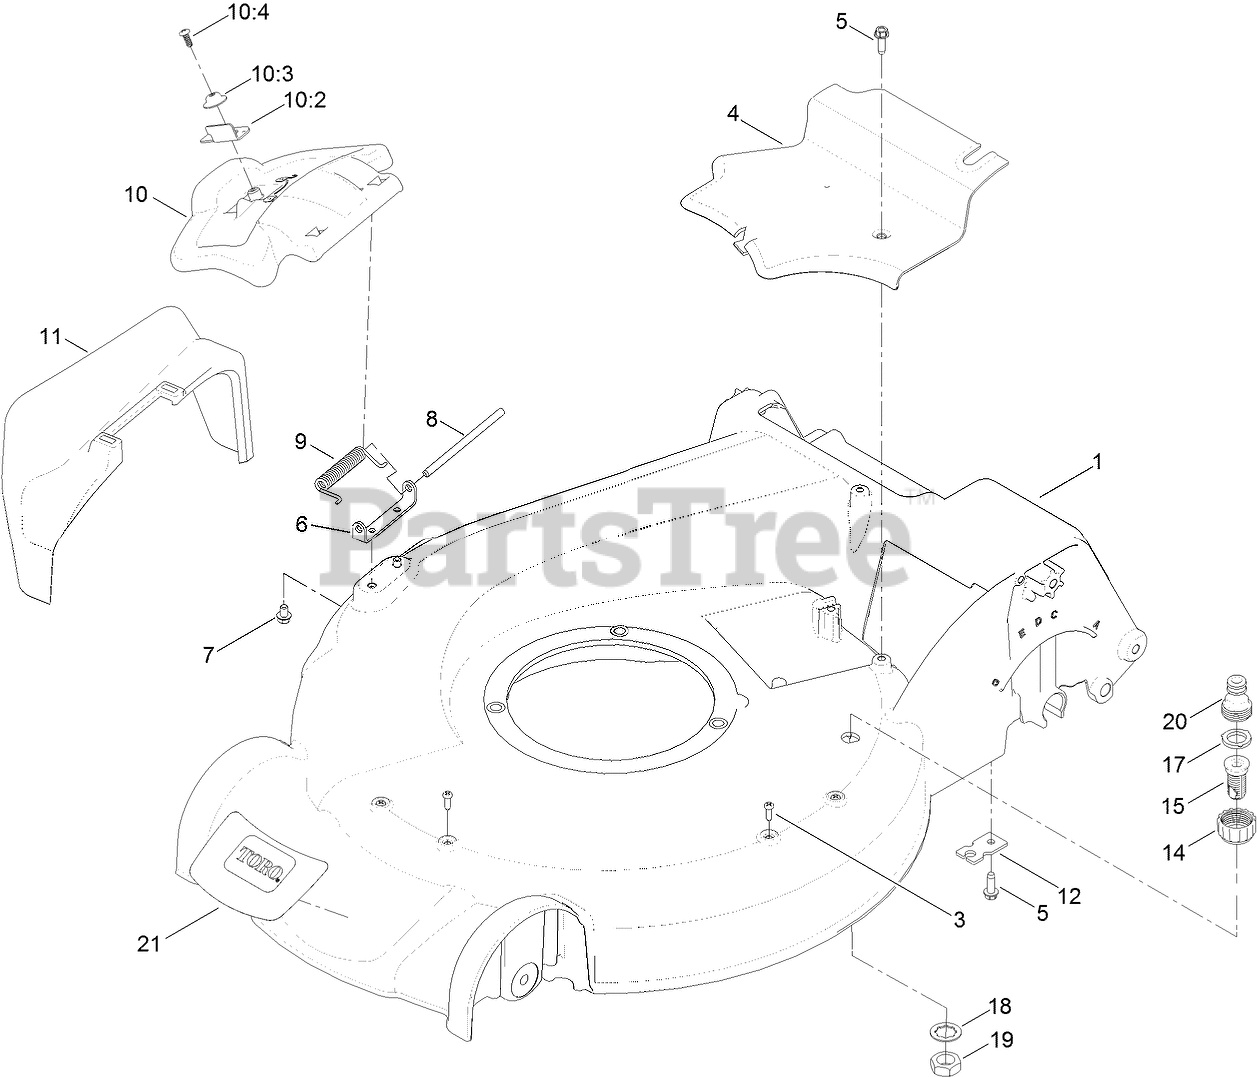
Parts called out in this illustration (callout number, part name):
1	HOUSING ASM
3	SCREW-PPH
4	COVER-BELT
5	SCREW-HWHTF
6	BRACKET-COVER
7	SCREW-HWH
8	ROD-COVER
9	SPRING-TORSION
10	DISCHARGE DOOR ASM
10:2	LATCH-DOOR
10:3	CAP-DOOR
10:4	SCREW-PLASTITE
11	CHUTE-DISCHARGE, SIDE
12	BRACKET-CABLE, TRACTION
14	COUPLING-HOSE, WASHOUT PORT
15	PORT-WASHOUT
17	WASHER-SEAL, WASHOUT PORT
18	WASHER-TOOTH, INTERNAL
19	NUT-JAM
20	ADAPTER-CONNECT, QUICK
21	DECAL-DECK
